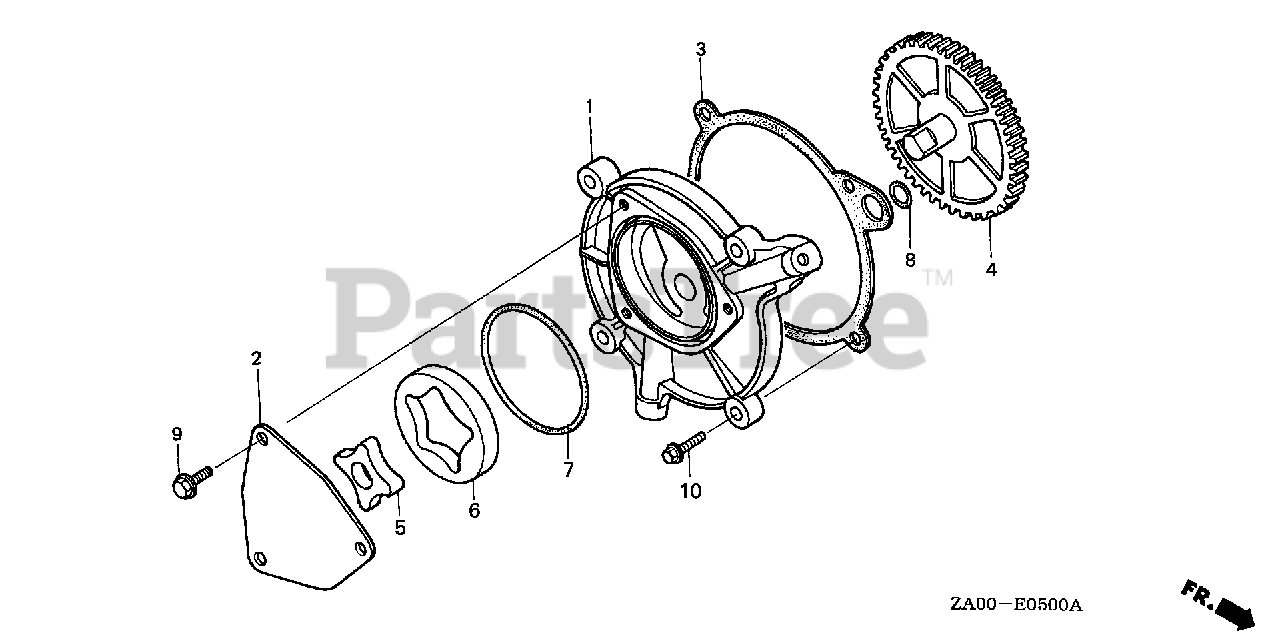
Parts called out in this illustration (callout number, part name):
1	BODY, OIL PUMP
2	COVER, OIL PUMP
3	GASKET, OIL PUMP
4	GEAR ASSY., OIL PUMP
5	ROTOR (INNER)
6	ROTOR (OUTER)
7	O-RING (45X2.5) (ARAI)
7	O-RING, PUMP COVER
8	O-RING (10.8X2.4) (ARAI)
9	BOLT, FLANGE (6X12)
10	BOLT, FLANGE (6X28)
